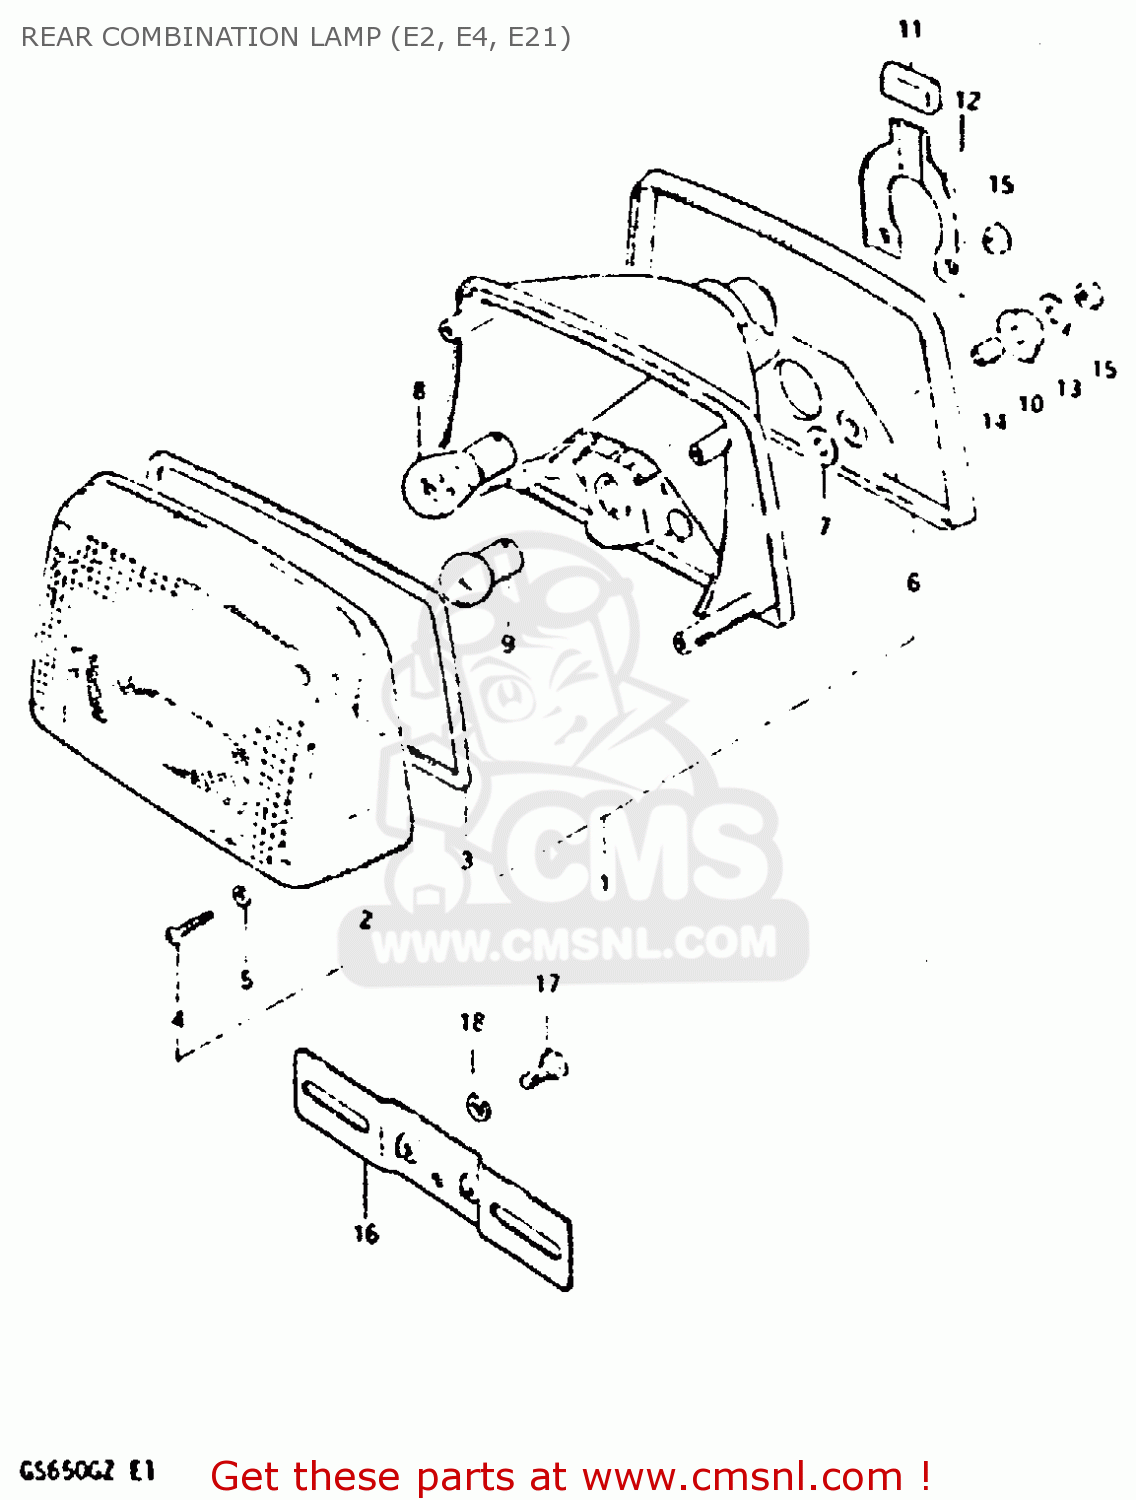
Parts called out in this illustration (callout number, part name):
1	LAMP ASSY, TAIL
2	LENS
3	GASKET (NAS)
4	SCREW,REAR COMBINATION LAMP
5	GASKET (NAS)
6	CUSHION,REAR COMBINATION LAMP
7	WASHER,REAR COMBINATION LAMP
8	BULB 12V21/5W
9	BULB
10	CUSHION,RR COMBINATION LAMP
11	CUSHION,REAR COMBINATION LAMP
12	PLATE
13	WASHER
14	SPACER (6.4X9X10.5)
15	NUT 6MM
16	BRACKET, LICENSE PLATE
17	BOLT
18	LOCK WASHER
